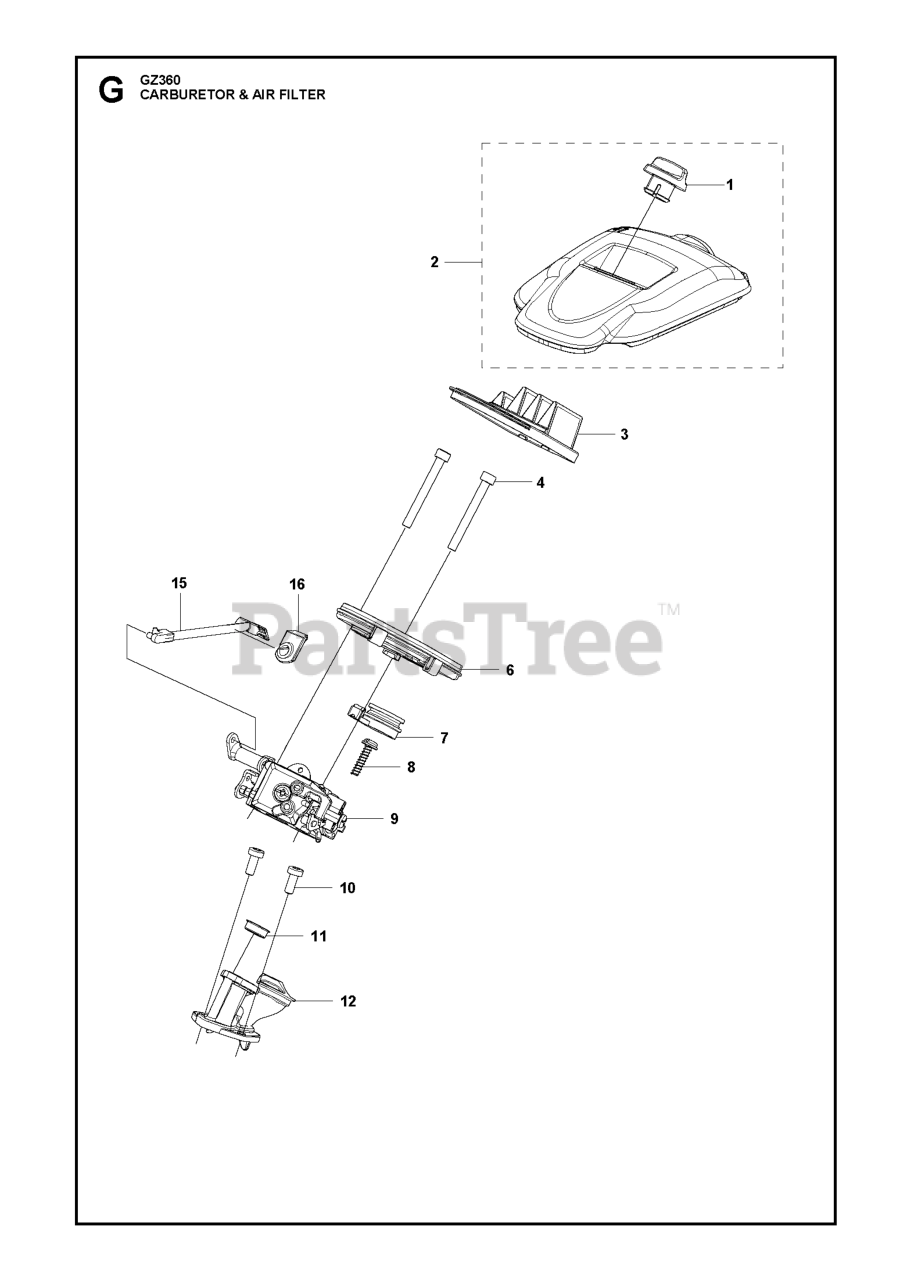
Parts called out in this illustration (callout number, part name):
1	KNOB Z335683322
2	AIR FILTER COVER ASSY GZ3600EZ
3	AIR FILTER 439/GZ3500L
4	BOLT
6	AIR FILTER BOTTOM BOTTOM 436/G
7	SEAL RPLS 848CE083G2
9	CARBURETTOR 439
12	INLET PIPE
15	CHOKE ROD GZ3500L
16	GROMMET CHOKE GZ3500L_BLACK
